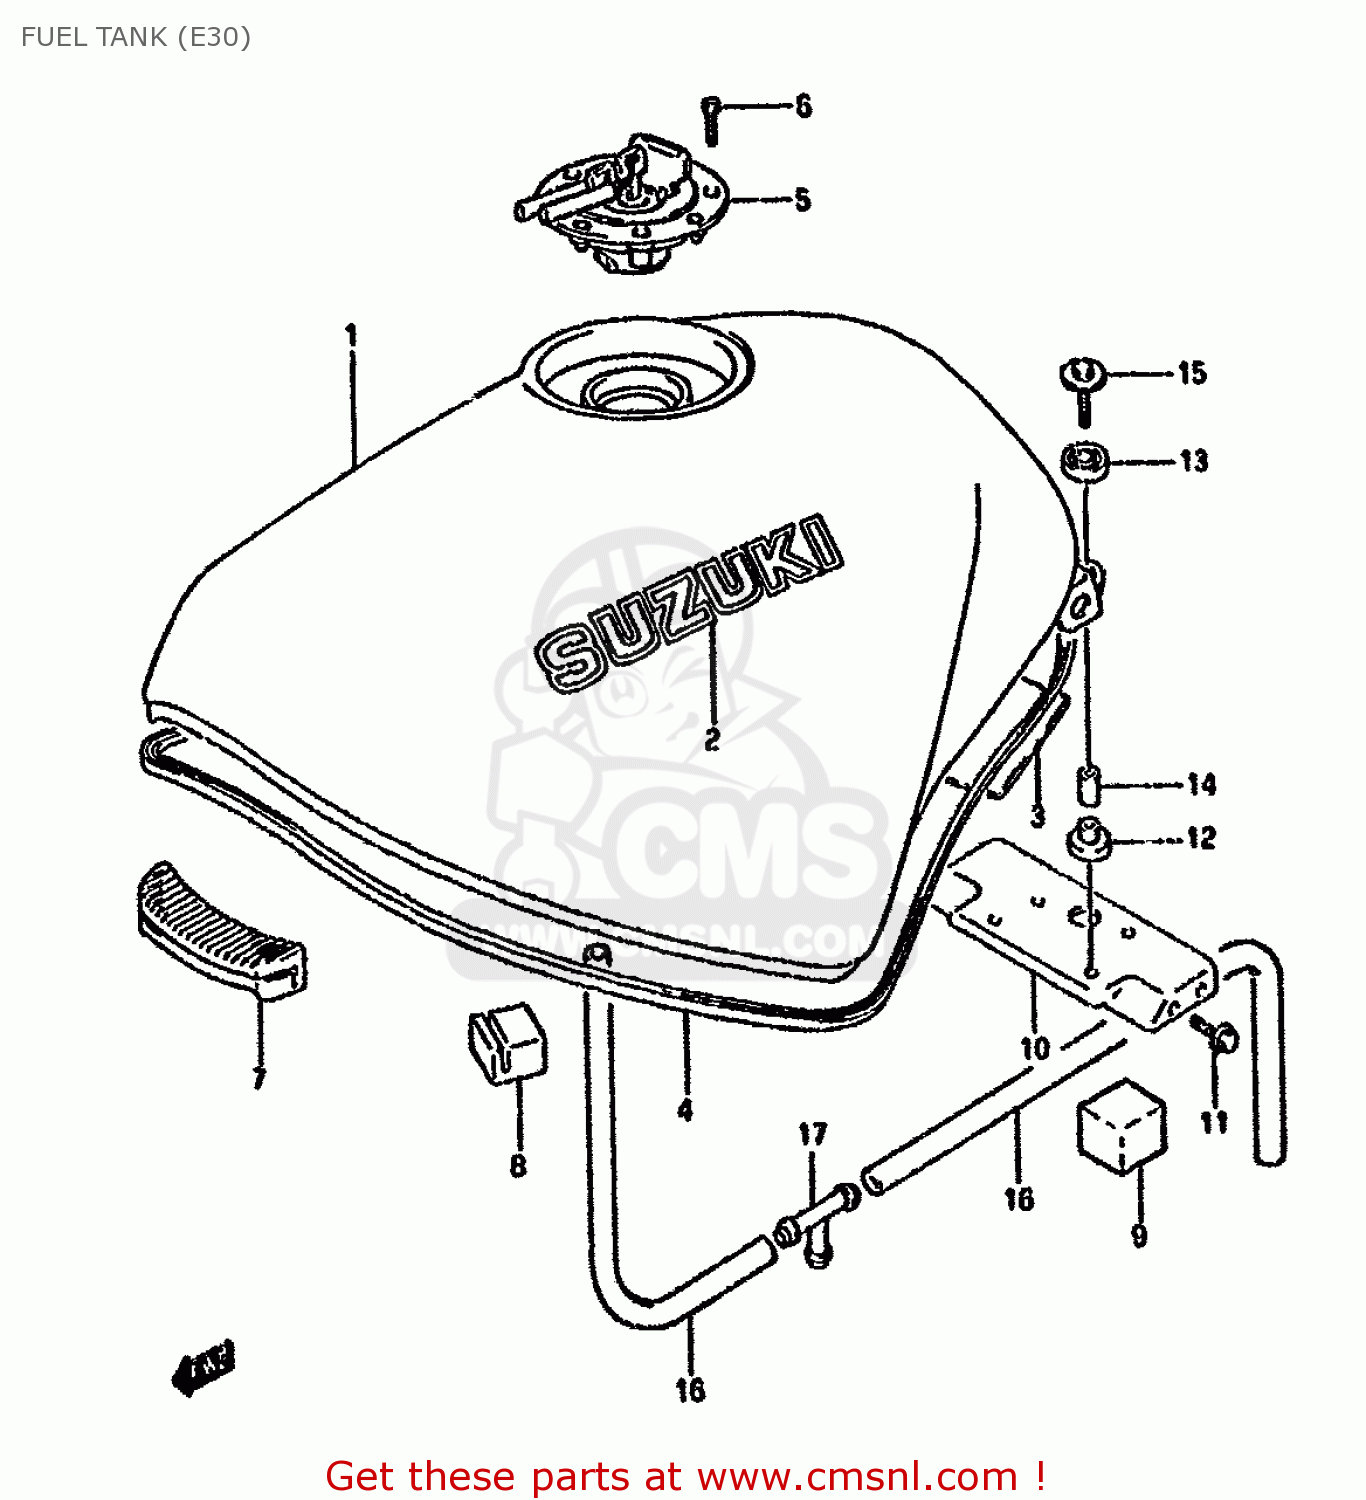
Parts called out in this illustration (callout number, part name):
1	TANK ASSEMBLY,FUEL
2	EMBLEM,FUEL TANK
3	SHEET,FUEL TANK RR
4	MOLDING,FUEL TANK
5	CAP SET,FUEL TANK
6	BOLT(5X20)
7	CUSHION,FUEL TANK FR
8	CUSHION,FUEL TANK SIDE
9	CUSHION,BATTERY 35X35X
10	BRACKET,FUEL TANK RR
11	BOLT 6X12
12	CUSHION
13	CUSHION
14	SPACER
15	BOLT
16	HOSE(7X10.2X600)
17	3 WAY
